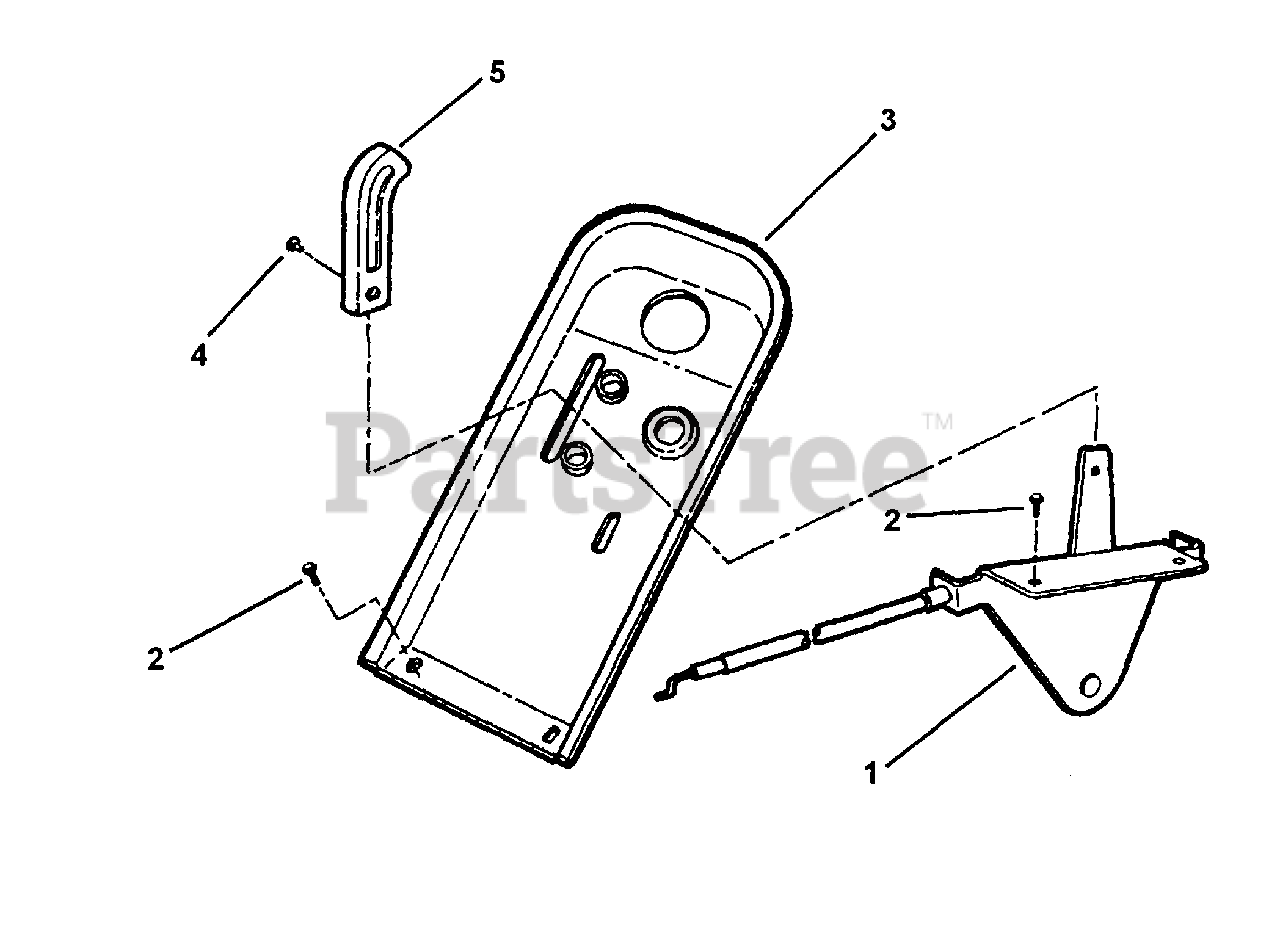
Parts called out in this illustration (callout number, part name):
1	CONTROL, Throttle 44.1" Conduit
1	CONTROL, Throttle 48.6" Conduit
2	SCREW, #10-24 x 1/2" Hex Washer Self-Tap (Torx)
3	COVER, Dash Panel
4	RIVET, Plastic Snap
5	KNOB, Throttle Control
